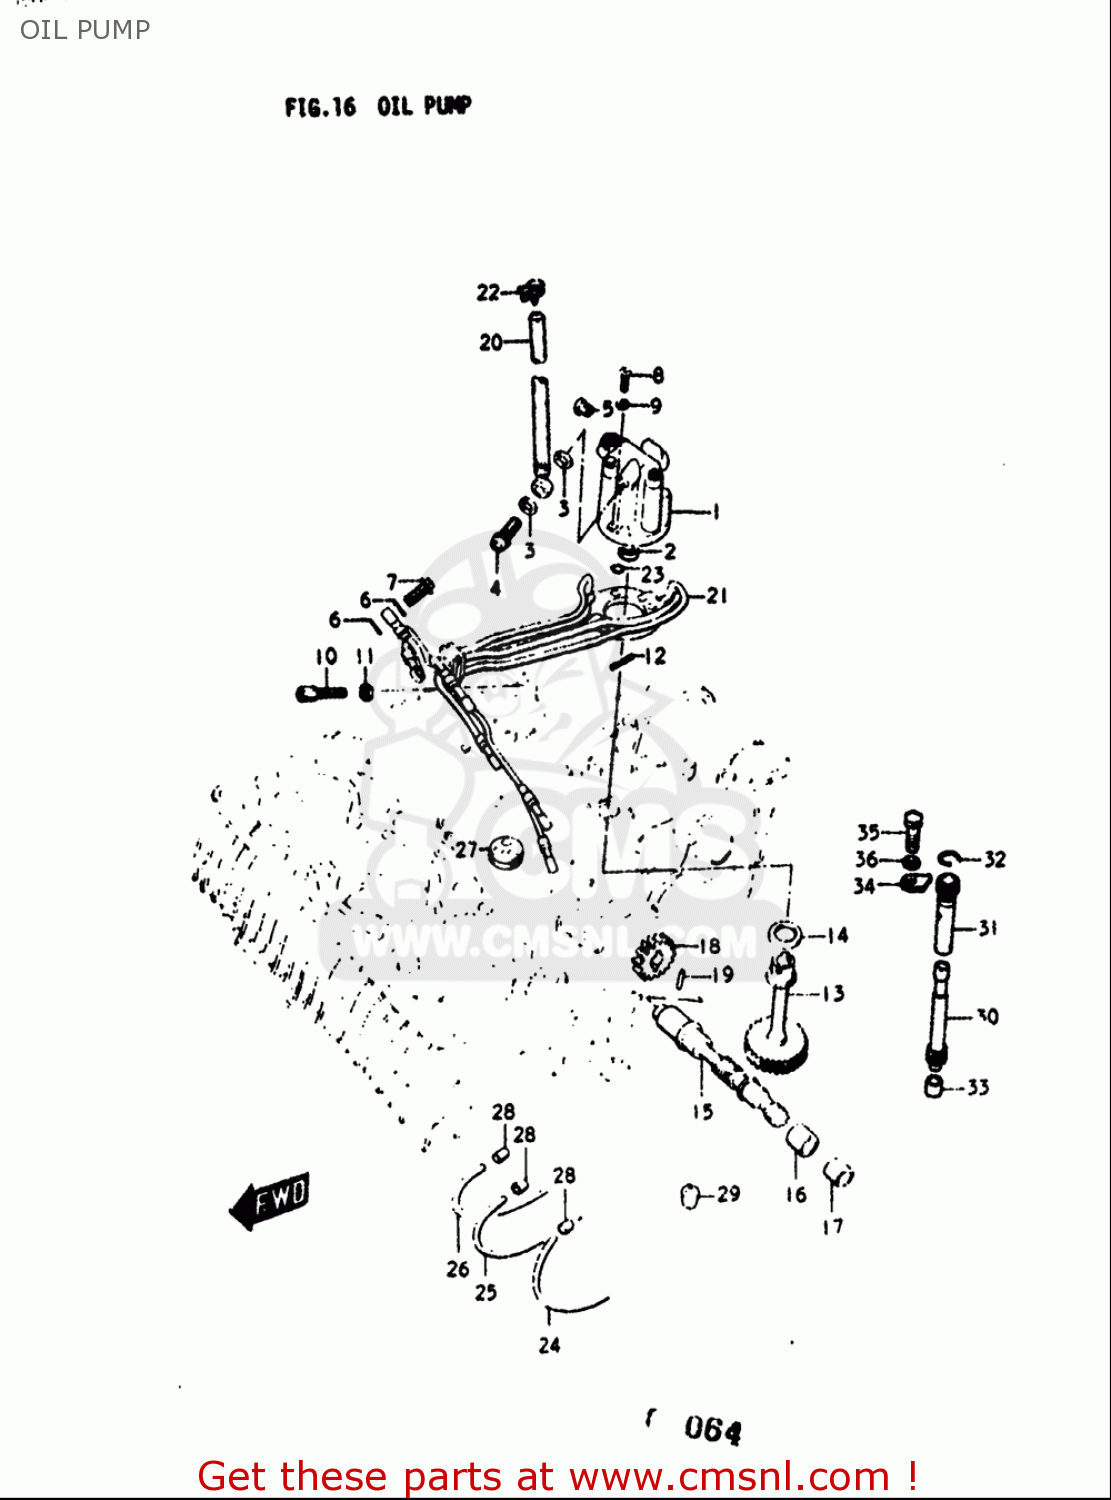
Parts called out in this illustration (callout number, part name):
2	SEAL,OIL(8X16X4)
3	GASKET(6.2X11X1).2 (NAS)
4	UNION BOLT
5	TERMINAL,CABLE
6	GASKET(6.2X11X1).2 (NAS)
7	UNION BOLT
8	SCREW
10	BOLT
11	NUT
12	PIN(3X13.8)
14	SHIM(14X22X1)
19	PIN(3X13.8)
22	CLIP
23	O RING(D:1.9,ID:3.8)
24	HOSE(2X5X600)
25	HOSE(2X5X600)
26	HOSE(2X5X600)
28	CLIP
32	O RING(D:1.3,ID:9.6)
34	PLATE,TACH DRIVE GEAR SLEEVE
35	BOLT
36	WASHER,LOCK
